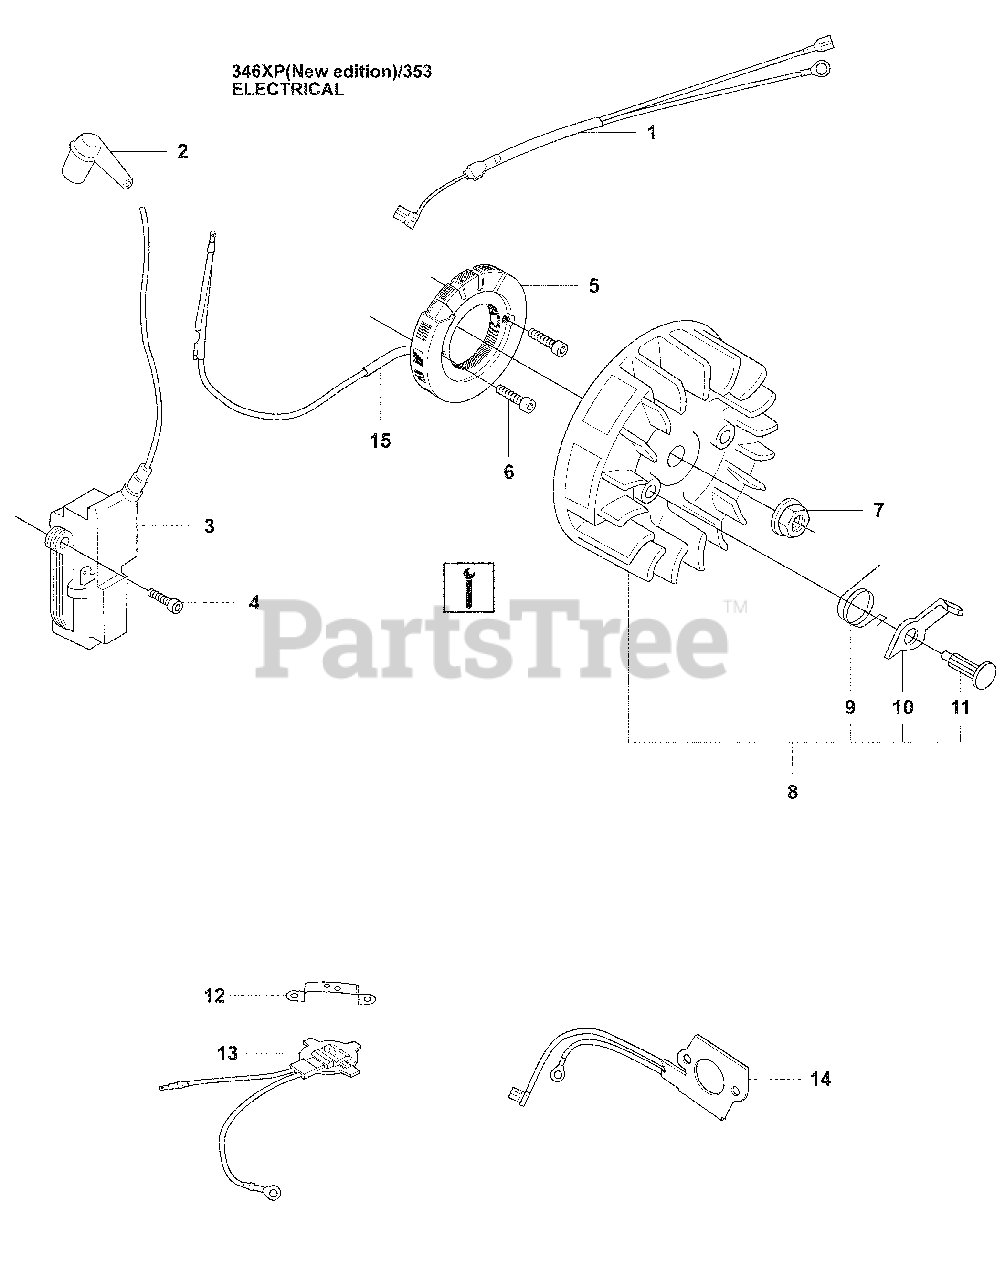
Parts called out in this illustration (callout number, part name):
1	WIRING ASSY
1	Wiring Assembly
2	Spark Plug Connection Kit
3	Ignition Module
5	GENERATOR
5	GENERATOR STATOR
7	Nut with Washer
8	Flywheel
8	FLYWHEEL (G)
8	RP FLYWHEEL
9	Spring
10	Pawl
11	Rivet
12	RETAINER
13	THERMOSTAT ASSY
14	Heating Plate
15	Cable Cover
